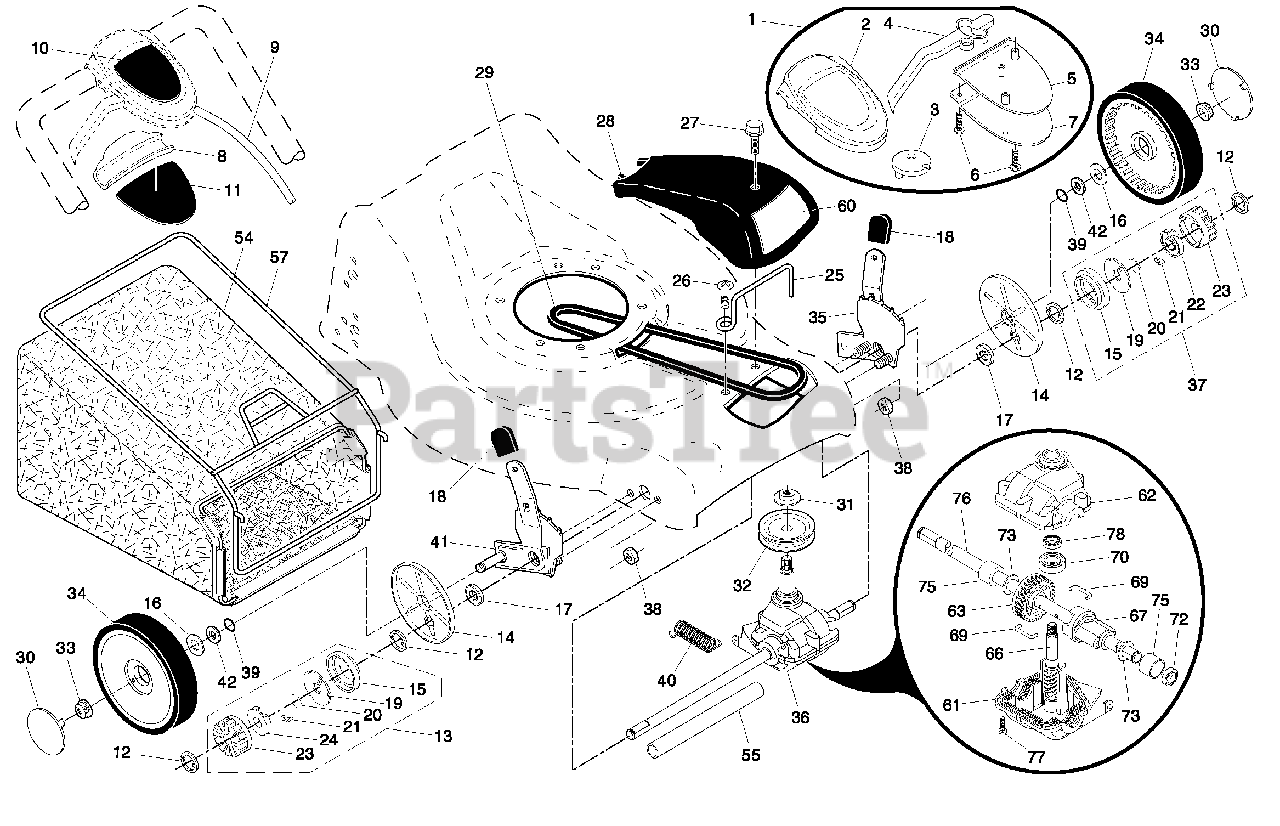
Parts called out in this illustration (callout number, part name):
2	Lower Handle
3	Control Bar
4	Engine Zone Control Cable
5	Handle Bolt
6	Handle Knob
7	Hairpin Cotter
8	Wire Tie
9	Kit, Rear Door
10	Pop Rivet
11	Support Bracket, LH
12	Support Bracket, RH
13	Screw 1/4-20 x 5/8
14	Handle Bracket Assembly, LH
15	Handle Bracket Assembly, RH
16	Spring, Rear Door, LH
17	Spring, Rear Door, RH
18	Keps Locknut 1/4-20
19	Rope Guide
20	Rear Skirt
21	Hinge Screw 1/4-20 x 1-1/4
22	Pulley, Engine
23	Key, Hi-Pro
25	Screw, Hex Head, Threaded, Rolled 3/8-16 x 2
26	Nut, Hex, Flangelock 3/8-16
27	Wheel & Tire Assembly, Rear, 14"
28	Bolt, Shoulder 5/16-18
30	Axle Arm Assembly, Rear, RH
31	Selector Knob
32	Selector Spring
33	Nut, Hex, Nylock 5/16-18
34	Axle Arm Assembly, Rear, LH
35	Hubcap
36	Bolt, Rear Door
37	Thread Cutting Screw w/Sems 5/16-18 x 3/4
38	Washer, Flat .34 x 1.38
40	Spacer, Engine
41	Screw, Debris Shield
43	Debris Shield
44	Kit, Housing
45	Danger Decal
46	Blade Adapter
47	Blade, 21"
48	Hardened Washer
49	Helical Washer 3/8
50	Blade Bolt, Hex Head, Grade 8
57	Screw #10-24 x 1/2
58	Upstop Bracket
59	Discharge Deflector
60	Hinge Bracket
61	Spring, Torsion
62	Rod, Hinge
63	Nut, Hex
64	Mulcher Door
65	O-Ring
66	Washer, Flat 3/8
67	Kit, Bushing, High Wheel
68	Bushing, Nylon, Black
96	Clip, Cable
96	Operator's Manual, English
96	Operator's Manual, French
96	Repair Parts Manual, English / French
